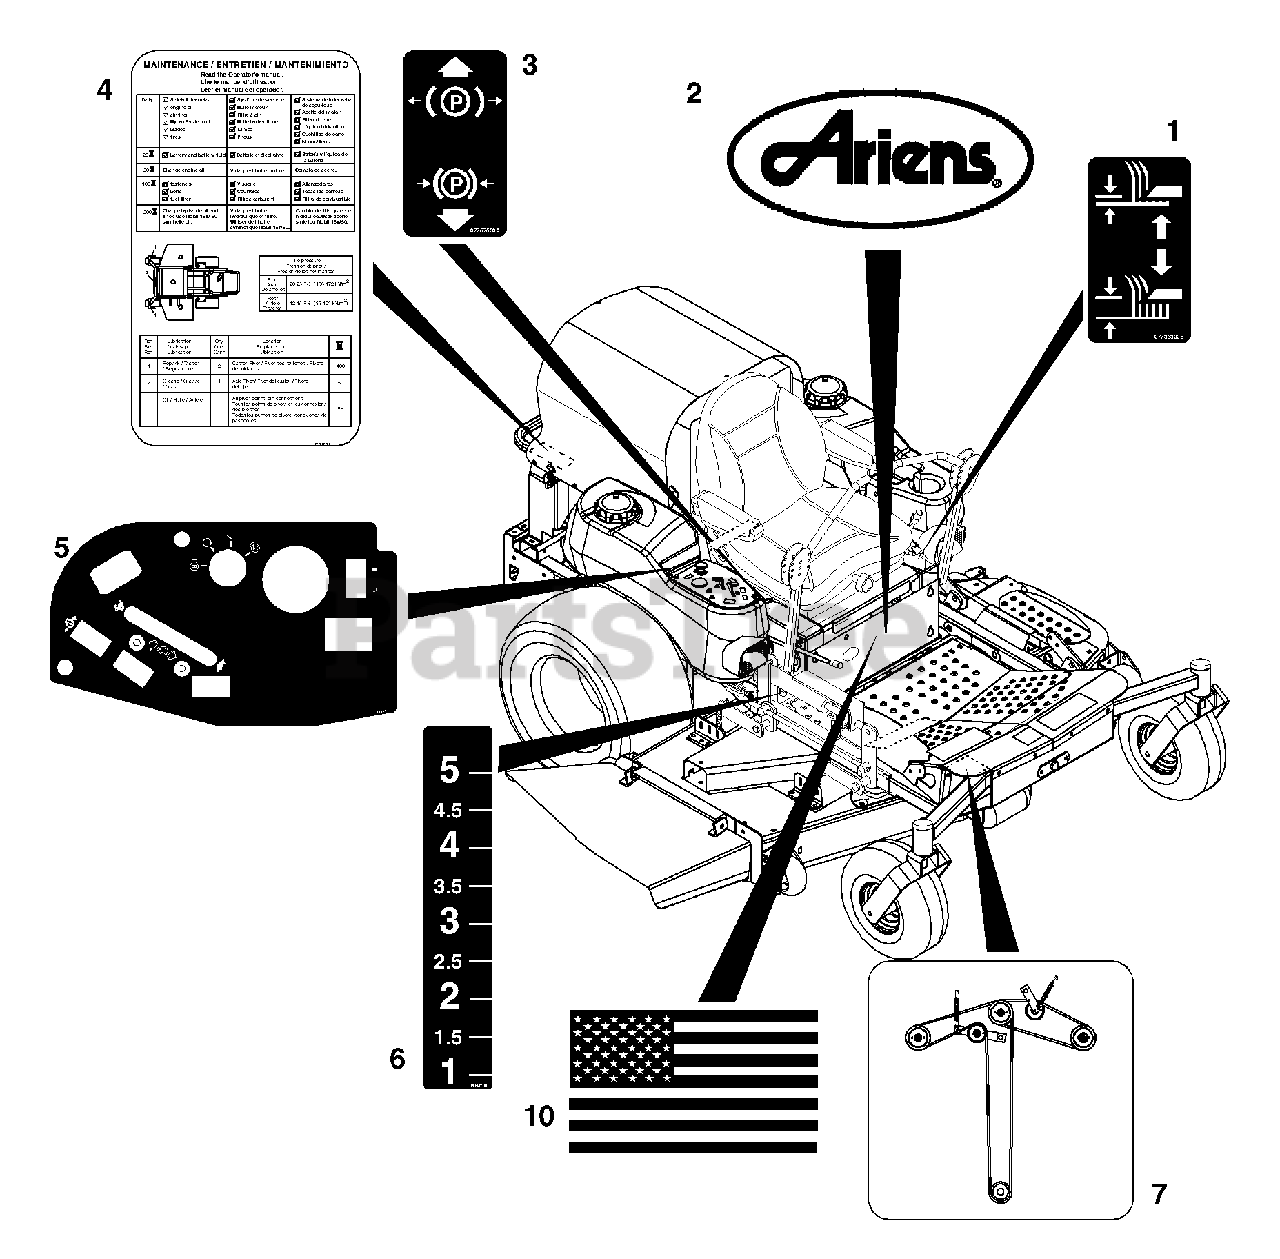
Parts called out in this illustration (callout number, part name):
1	DECAL- LIFT LEVER
2	DECAL, ARIENS
3	DECAL, PARKING BRAKE LEVER
4	DECAL- SERVICE INSTRUCTIONS
5	DECAL, CONTROL PANEL L/C - GAS
6	DECAL, HEIGHT OF CUT
7	DECAL, GRAVELY BELT DIAGRAM
8	DECAL, PM-260Z
9	DECAL, 60
10	DECAL, AMERICAN FLAG
